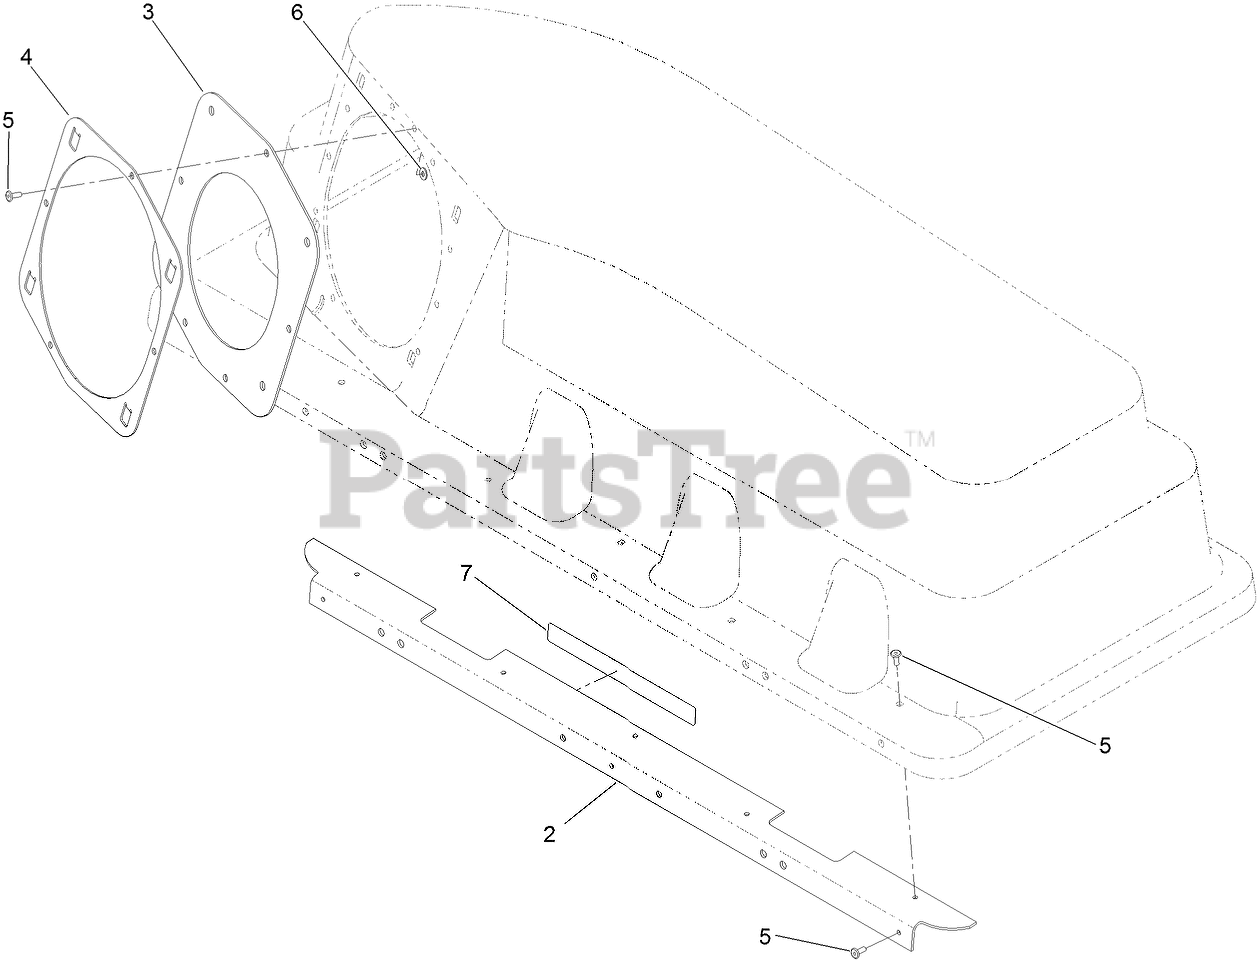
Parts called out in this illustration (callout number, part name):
2	STIFFENER-BAGGER TOP
3	GASKET
4	RING-RETAINER
5	RIVET-BLIND
6	WASHER-FLAT
7	DECAL-CAUTION, BAGGER
